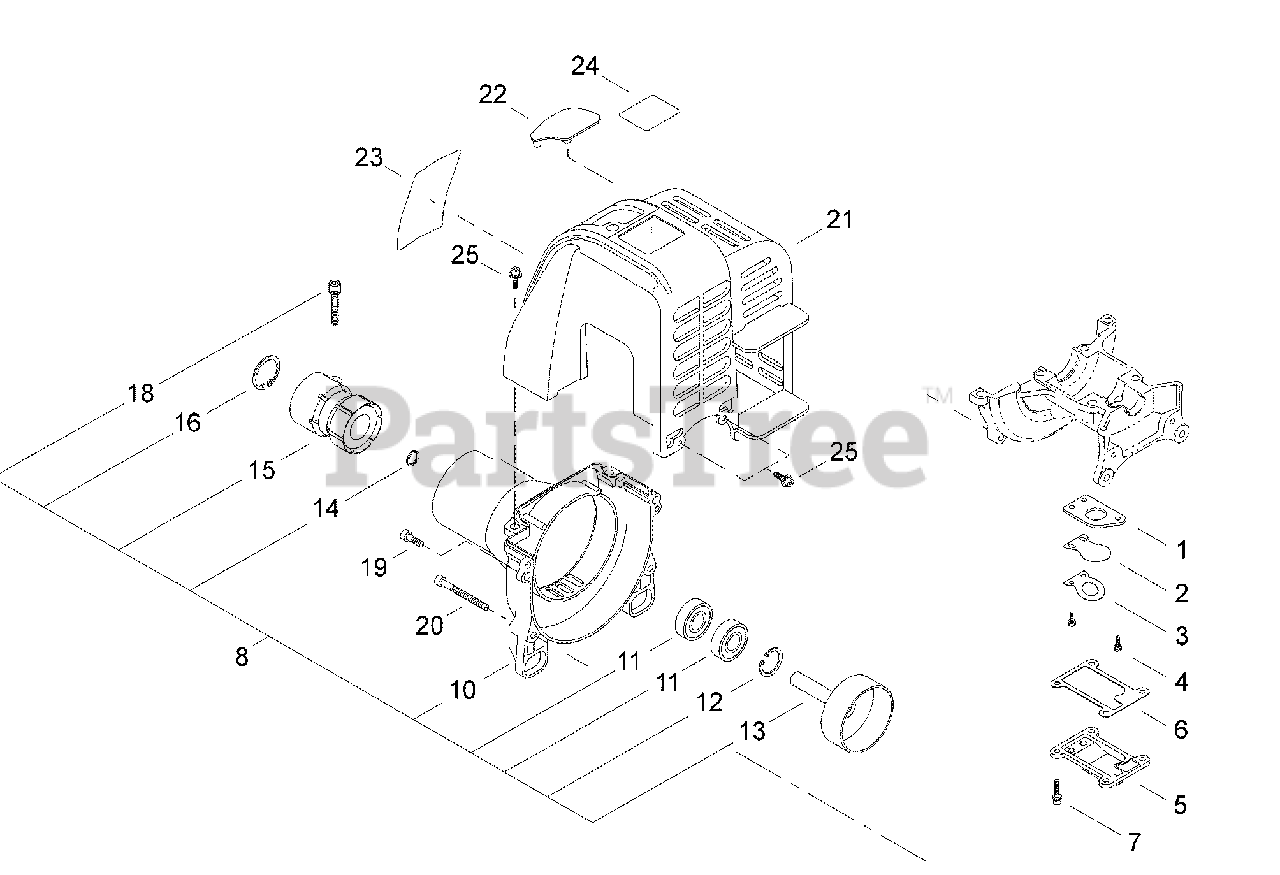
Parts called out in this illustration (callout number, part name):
1	PLATE, REED BACKING
2	VALVE, REED
3	STOP, REED VALVE
4	SCREW M3×10
5	COVER, REED VALVE
6	GASKET, REED VALVE
7	BOLT M4×12
8	COVER ASSY, FAN
10	COVER, FAN
11	BEARING, BALL 6000ZZ
12	RING, SNAP Ø26
13	DRUM, CLUTCH
14	RING, SNAP WR10
15	CUSHION, AV
16	RING, SNAP Ø40
18	BOLT M5×22
19	BOLT 5×16
20	BOLT M5×45
21	COVER, ENGINE
22	COVER, SPARK PLUG
23	LABEL, C4 SHINDAIWA
24	LABEL, C2510
25	BOLT M4×16
